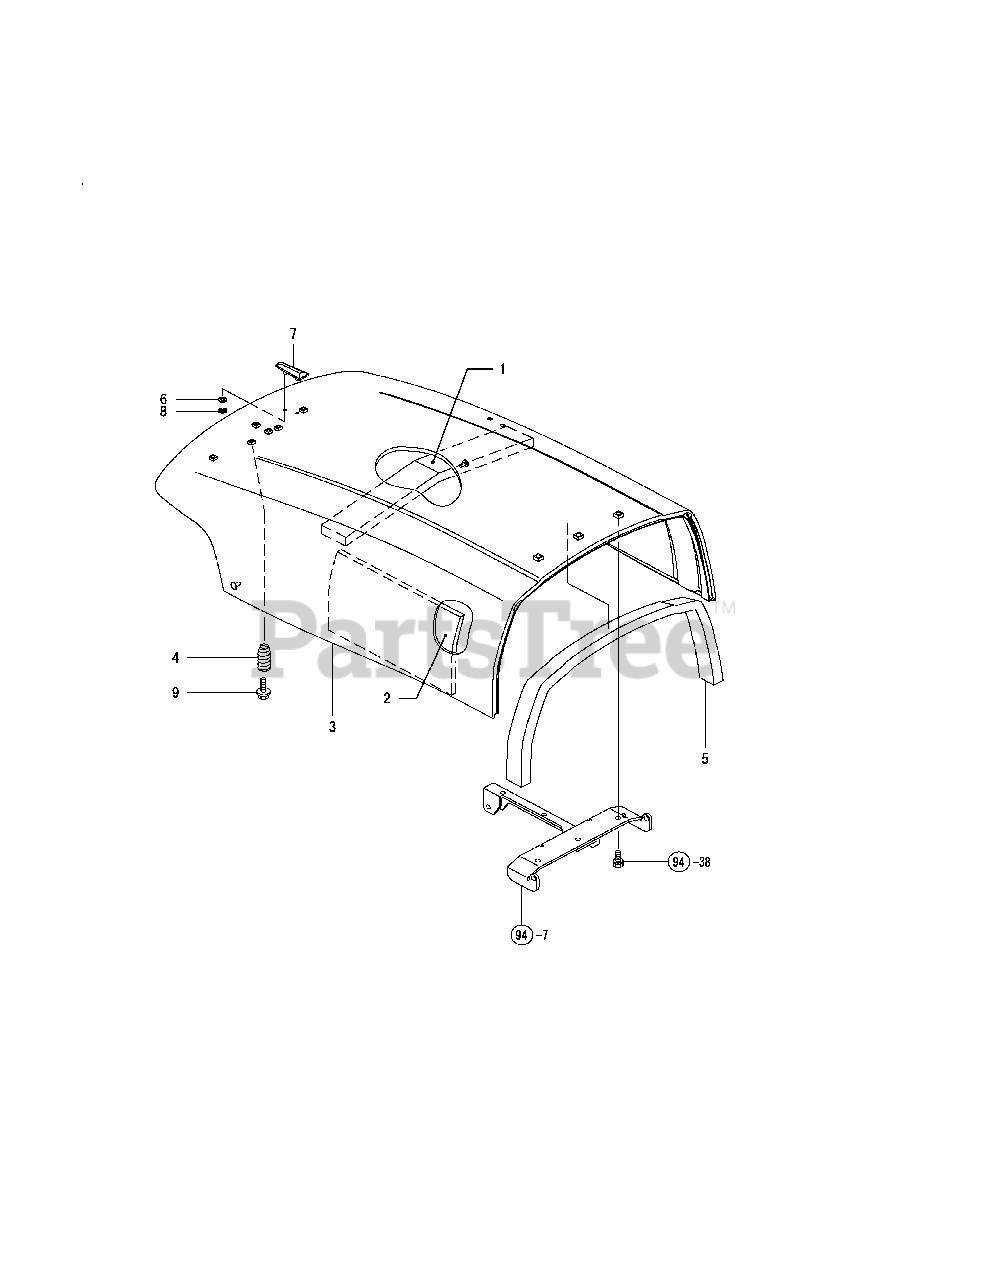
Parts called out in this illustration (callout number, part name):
1	URETHANE, HOOD UPPER
2	URETHANE, HOOD UPPER
8	NUT M5, SPEED
9	BOLT M 6X 16 PLATED
